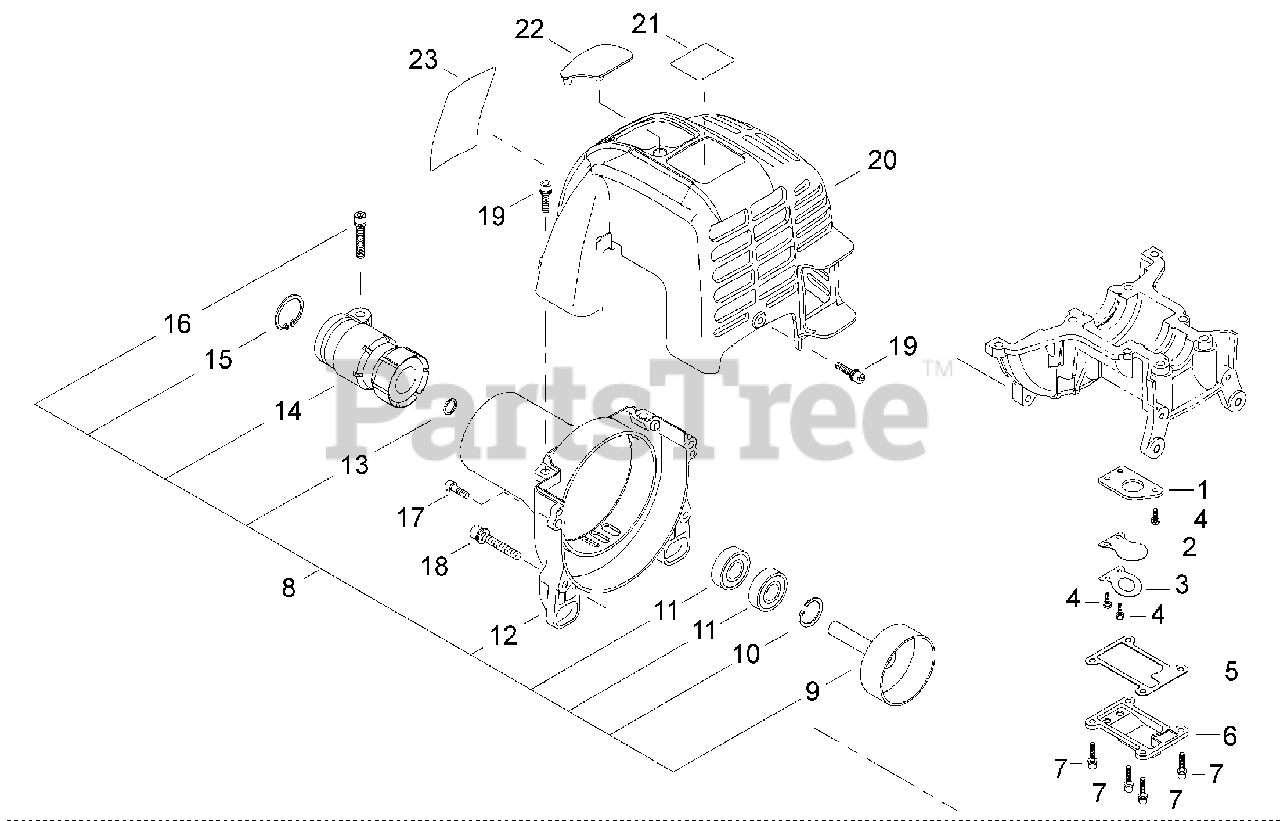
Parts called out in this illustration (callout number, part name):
1	PLATE, REED BACKING
2	VALVE, REED
3	STOP, REED VALVE
4	SCREW M3×10
5	GASKET, REED VALVE
6	COVER, REED VALVE
7	BOLT M4×14
8	COVER ASSY, FAN
9	DRUM, CLUTCH
10	RING, SNAP Ø28
11	BEARING, BALL 6001 DDU C3
12	COVER, FAN
13	RING, SNAP Ø12
14	CUSHION, AV
15	RING, SNAP Ø42
16	BOLT M5×22
17	BOLT 5×16
18	BOLT M5×40
19	BOLT M4×14
20	COVER, ENGINE
21	LABEL, P3410
22	COVER, SPARK PLUG
23	LABEL, C4 SHINDAIWA
